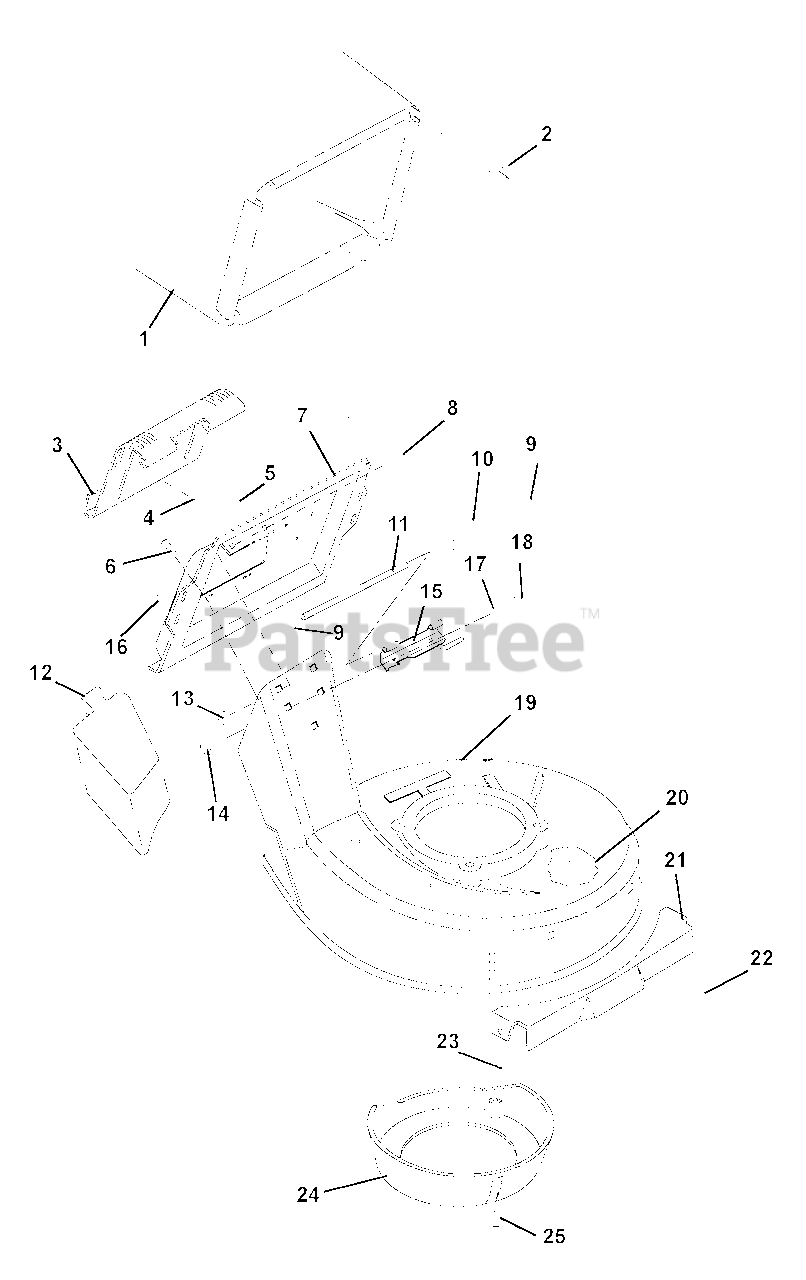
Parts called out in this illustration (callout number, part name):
1	Bag, Consumer Black
2	Frame, Bagger
3	Door, Catcher Plate
4	Button Bumper
6	Screw, Tapping 10-24 x .38 Pan Head
7	Plate, Catcher
8	Bolt, Round Head Square Neck .25-20 x .38
9	Nut, Push
10	Spring, Torsion .120 x .68 x 3.09
11	Pin, Door
12	Mulch Master Mulcher Accessory
13	Nut, Locking Flange .25-20
14	Bolt, Round Head Square Neck .25-20 x .75 Grade 5
15	Base, Hinge
16	Nut, Locking Flange .25-20
17	Washer, Locking .25 x .077
18	Nut, Hex .25-20
19	Mower Pan Head with Decals - Self-Propelled
20	Bolt, Round Head Square Neck .31-18 x .50 Grade 5
21	Front Panel
22	Nut, Spin Lock Flange .312-18
23	Grommet, Plastic
24	Baffle, Center
25	Screw, Tapping 10-16 x .62 Hex Washer Head
